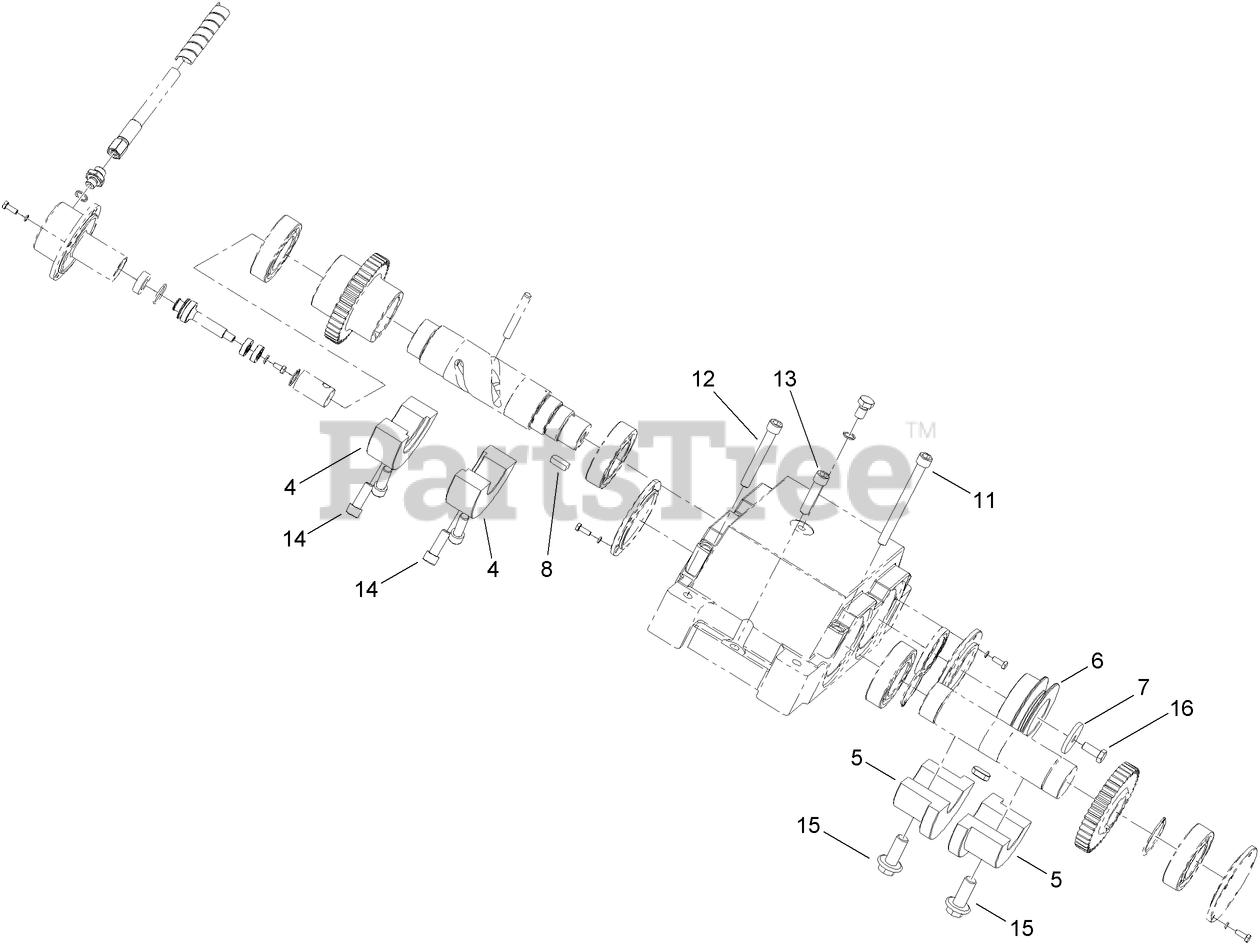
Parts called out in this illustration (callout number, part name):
4	WEIGHT I
5	WEIGHT I I
6	PULLEY
7	WASHER
8	ADAPTER
16	SCREW-HH
